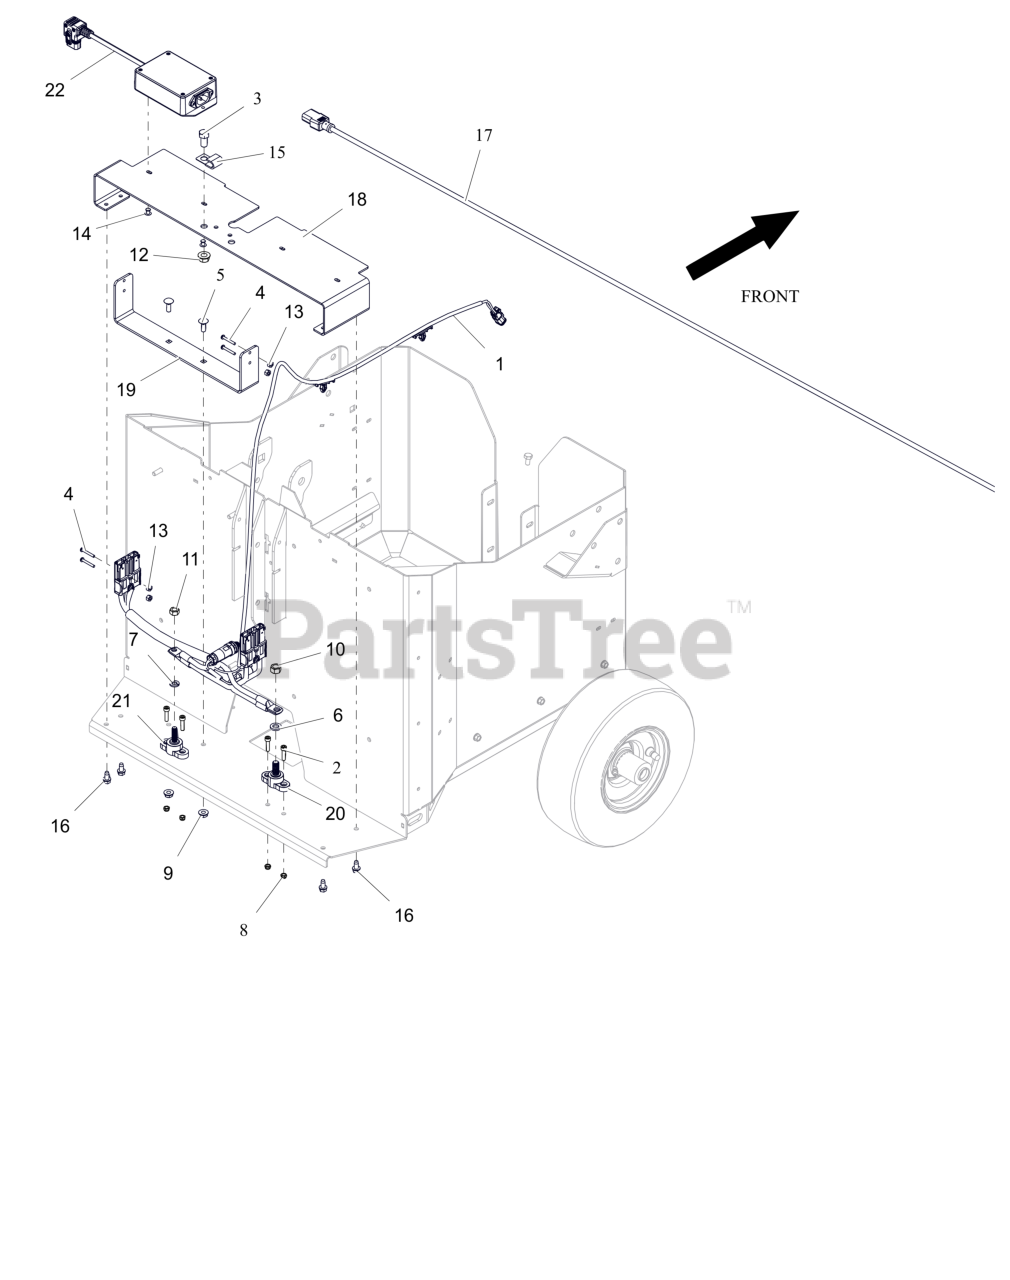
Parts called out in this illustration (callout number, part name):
1	HARNESS, OFFBOARD CHARGER
2	SCR, SKH M5-.8 X 20 GR12.9 ROHS
3	BLT,HEX .38-16X.75 G5 ZCC
4	SCR, PH PAN HD #6-32X1.000 ZCC
5	BLT, RHSN .25-20X.750 G5 ZCC
6	WSHR,LK-REG .375X.094 ZCC
7	WSHR,LK-REG .312X.078 ZCC
8	NUT, LK-NYL M5-0.8 GR8.8 ZC120
9	NUT-SPNLK-FLG .25-20 ZC120
10	NUT-LK-CTR .38-16 ZC120
11	NUT,LK-CTR .31-18 GA ZCC
12	NUT-LK-CTR-FLG .375-16 GF ZCC
13	@NUT-LK-NYL 6-32 W/INSRT YWZC
14	RVT, POP .1875 ZCC
15	J-CLAMP
16	SCR-TAP .25-20X.50 HWH ZCC
17	CORD, POWER EU 220V AC
18	PLATE, GROUND SEPARATION (BLACK)
19	PLATE, CHARGER PLUG MNT (BLACK)
20	STUD, POSITIVE POWER
21	STUD, NEGATIVE POWER
22	FILTER ,EMI, 120/250V,50-60HZ
